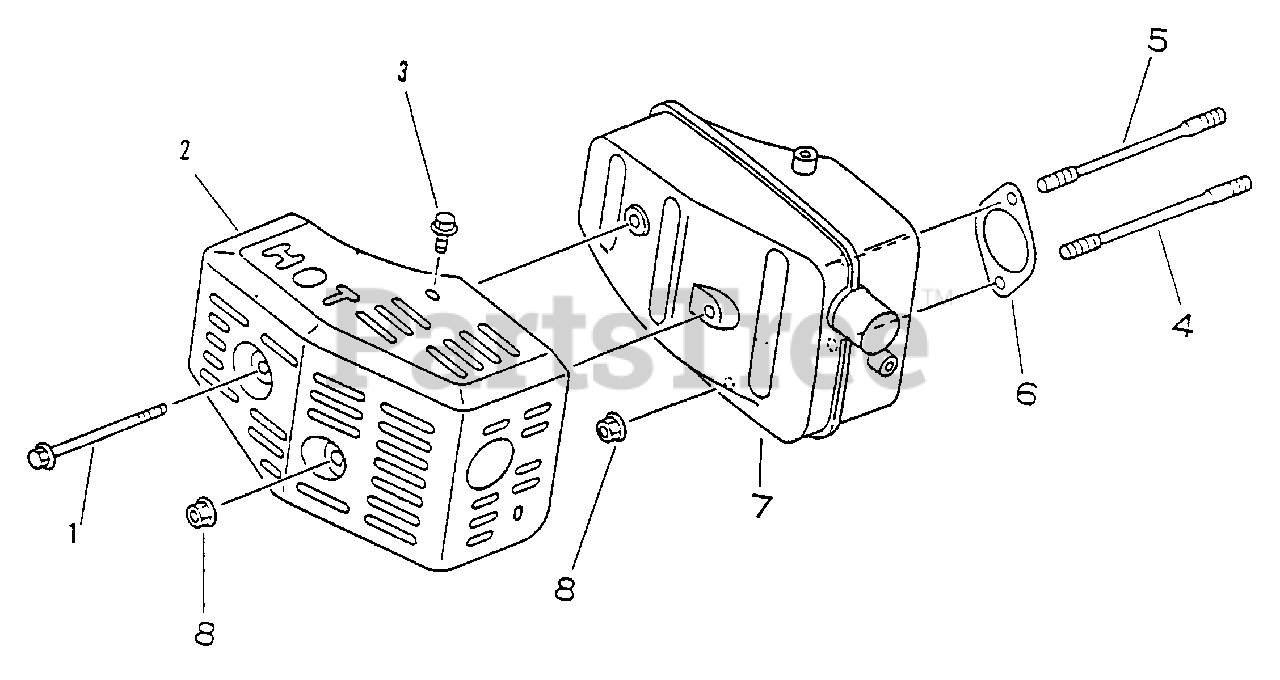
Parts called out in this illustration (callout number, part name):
1	BOLT - 6×80
2	COVER, MUFFLER
3	SCREW - 6×10
4	BOLT, STUD
5	BOLT, STUD
6	GASKET, MUFFLER
7	MUFFLER
8	NUT, FLANGE M8
